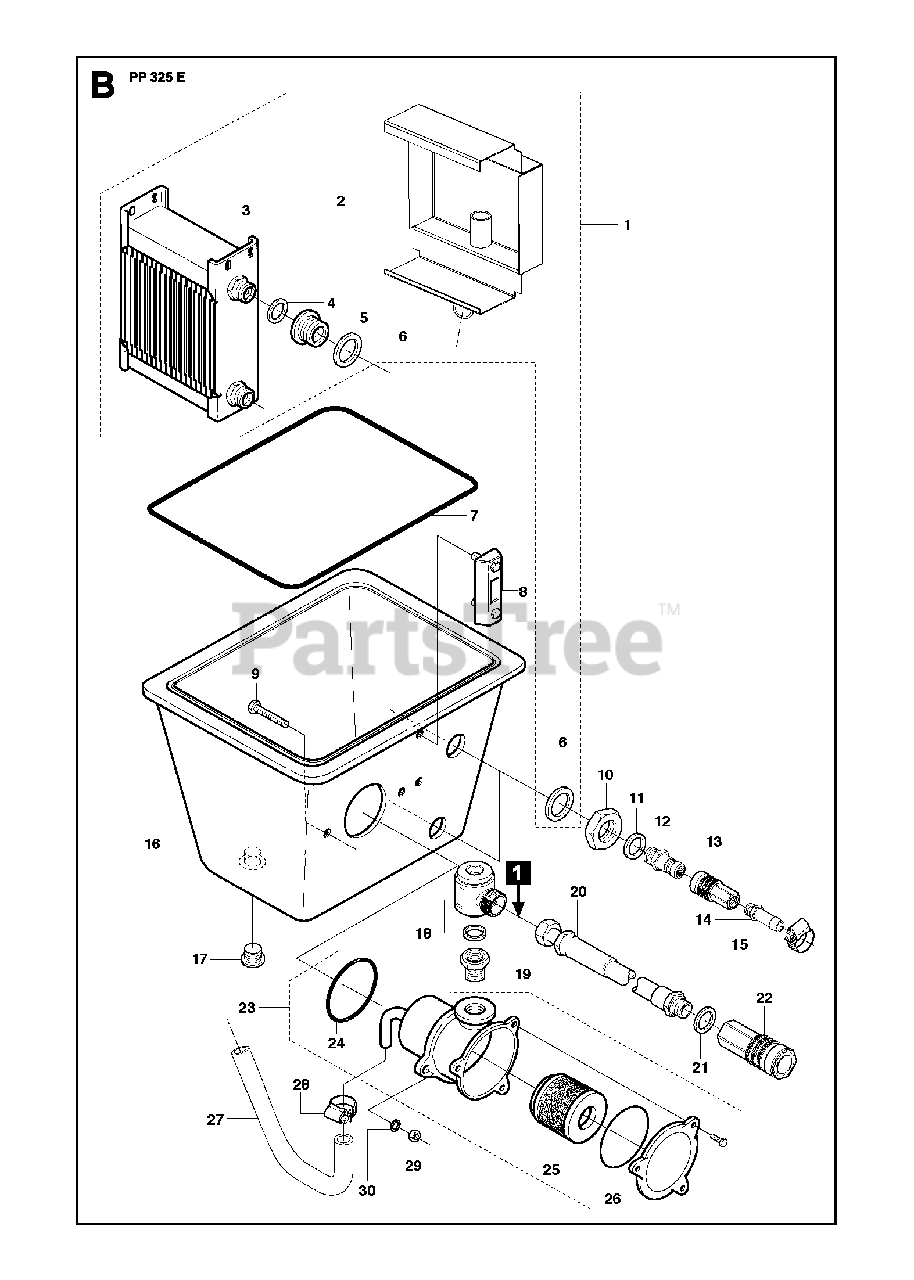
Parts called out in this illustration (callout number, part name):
16	HYDRAULIC TANK
29	HEXAGON NUT
30	WASHER
